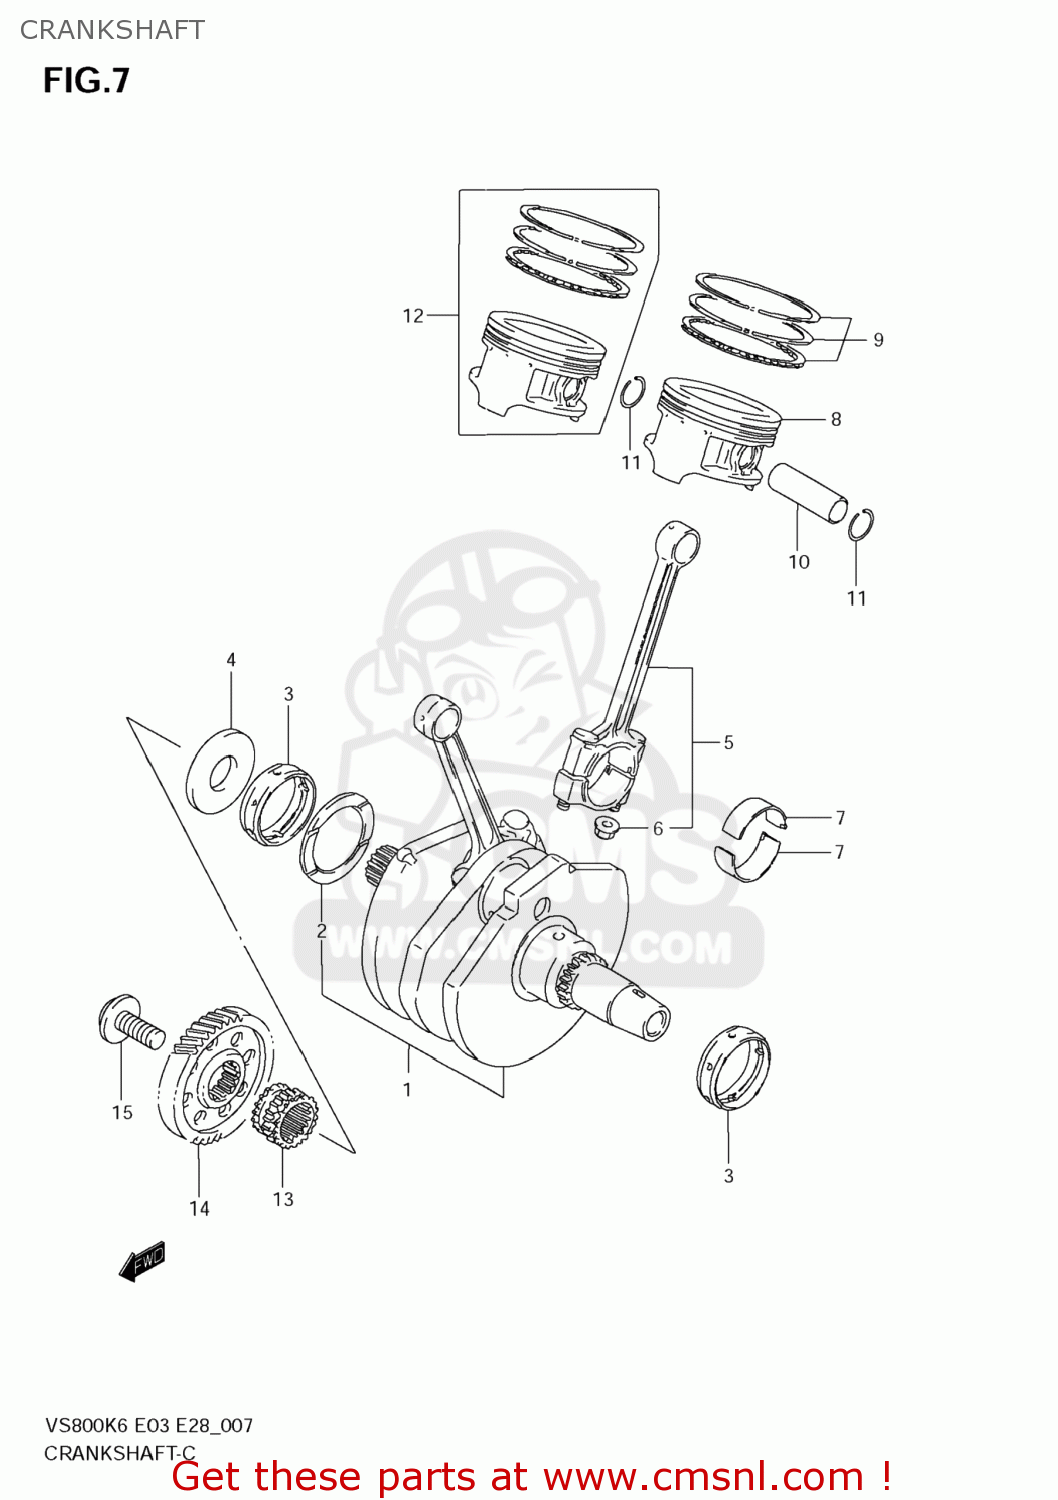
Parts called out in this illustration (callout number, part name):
1	CRANKSHAFT SET
2	WASHER(48.1X64X1.94)
3	METAL,CRANKSHAFT
4	WASHER,CRANK THRUST
5	CONNECTING ROD ASSY
6	NUT
7	BEARING,CRANK PIN
8	PISTON
9	RING SET,PISTON
10	PIN,PISTON
11	CIRCLIP,PISTON PIN
12	PISTON SET(OS:0.5)
13	SPROCKET,CAM CHAIN DRIVE,R
14	GEAR,PRIMARY DRIVE
15	BOLT(12X28)
